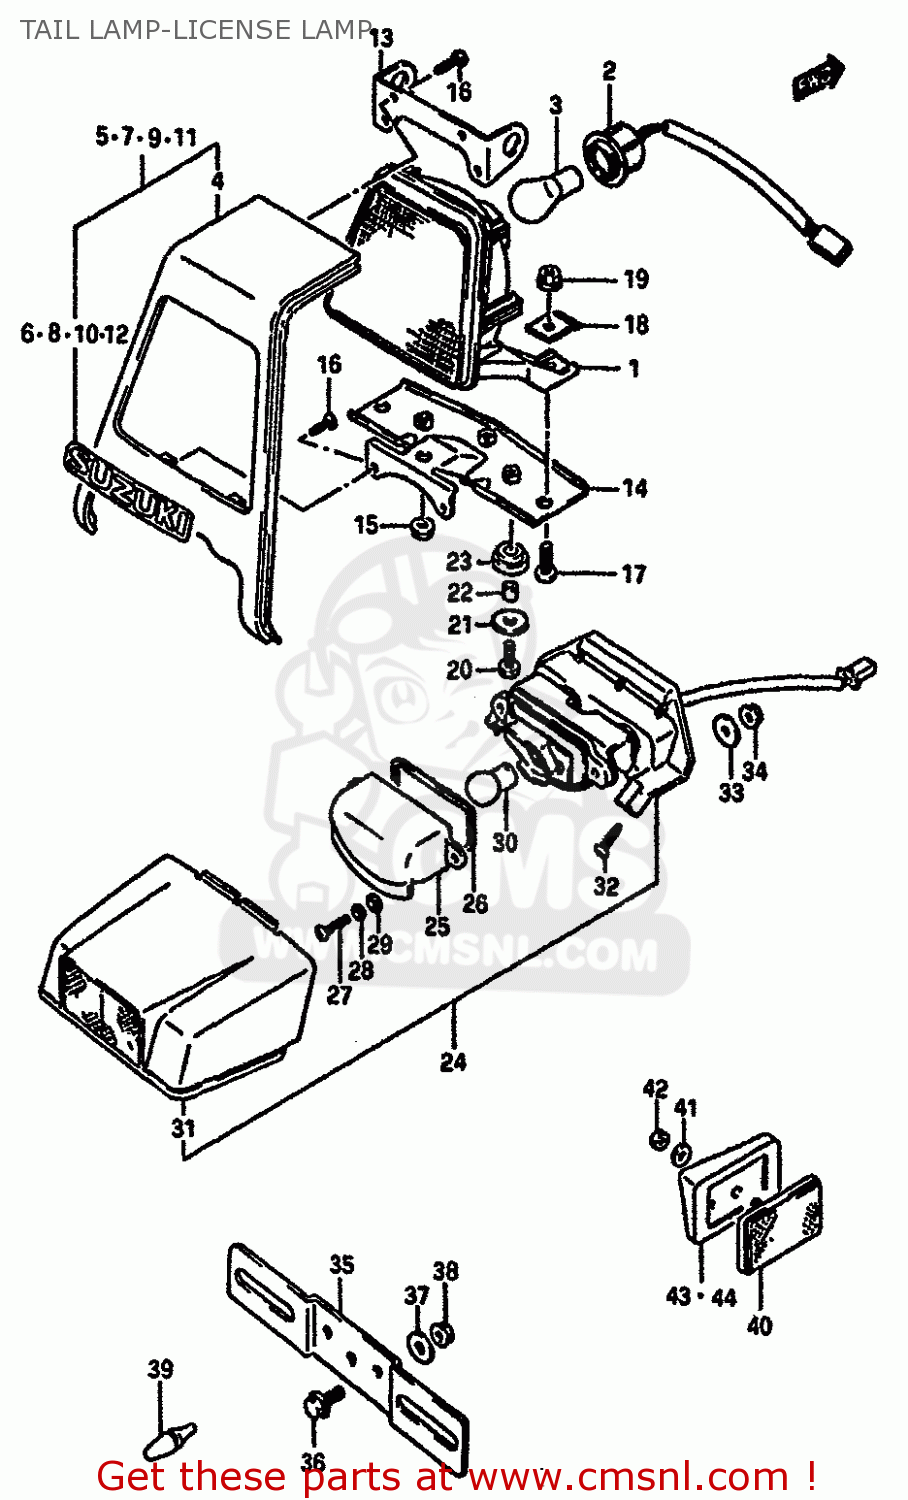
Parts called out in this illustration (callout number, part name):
1	UNIT,REAR COMBINATION LAMP
2	SOCKET & CORD ASSEMBLY
3	BULB(12V21/5W)
4	COVER,TAIL LAMP
5	COVER,TAIL LAMP
6	EMBLEM
7	COVER,TAIL LAMP
8	EMBLEM
9	COVER,TAIL LAMP
10	EMBLEM
11	COVER,TAIL LAMP
12	EMBLEM
13	PLATE
14	BRACKET
15	NUT
16	SCREW
17	SCREW
18	PLATE,TAIL LAMP
19	NUT
20	BOLT,M6X1X20
21	WASHER
22	SPACER (6.1X9X7.5)
23	CUSHION
24	LAMP ASSY,LICENSE
25	LENS,LICENSE LAMP
26	GASKET,LICESE LAMP (NAS)
27	SCREW
28	WASHER,LOCK 4M
29	WASHER 4MM
30	BULB
31	COVER,LICENSE LAMP
32	SCREW
33	WASHER (5.5X20X1.2)
34	NUT
35	PLATE,RR LICENSE
36	BOLT
37	WASHER
38	NUT
39	CUSHION
40	REFLEX REFLECTOR,REAR SIDE
41	WASHER(5.2X16X1)
42	NUT ,5MM
43	SPACER,REAR SIDE,REAR,RIGHT
44	SPACER,REAR SIDE,REAR,LEFT
